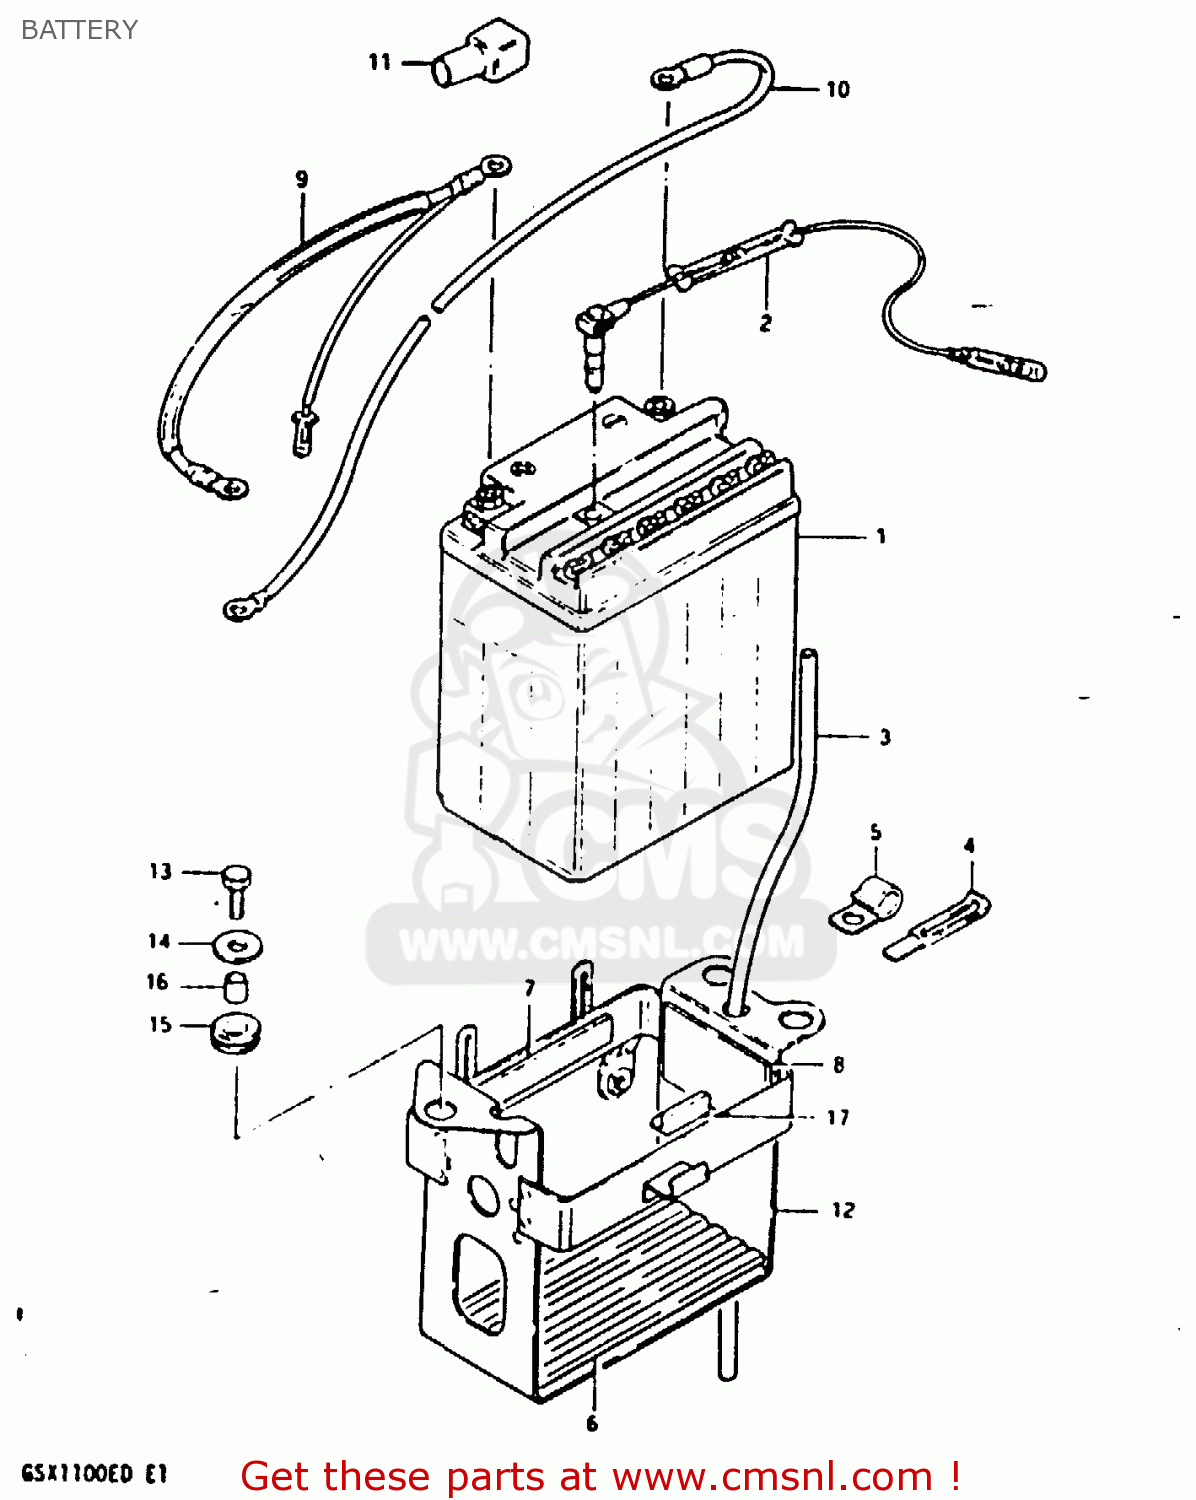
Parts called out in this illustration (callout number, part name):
1	BATTERY ASSEMBLY (12V)
2	SENSOR,BATTERY LEVEL
3	HOSE,BATTERY EXHAUST
4	CLAMP L:35
5	CLAMP
6	PROTECTOR,BATTERY
7	PROTECTOR(20X90)X4
8	PROTECTOR(170X95X3.0)
9	WIRE,BATTERY PLUS
10	LEAD WIRE,BATTERY(-)
11	CAP,TERMINAL
12	HOLDER,BATTERY
13	BOLT, UPPER
14	WASHER
15	CUSHION
16	SPACER(6.1X9X7.5)
17	CUSHION,FRAME COVER
